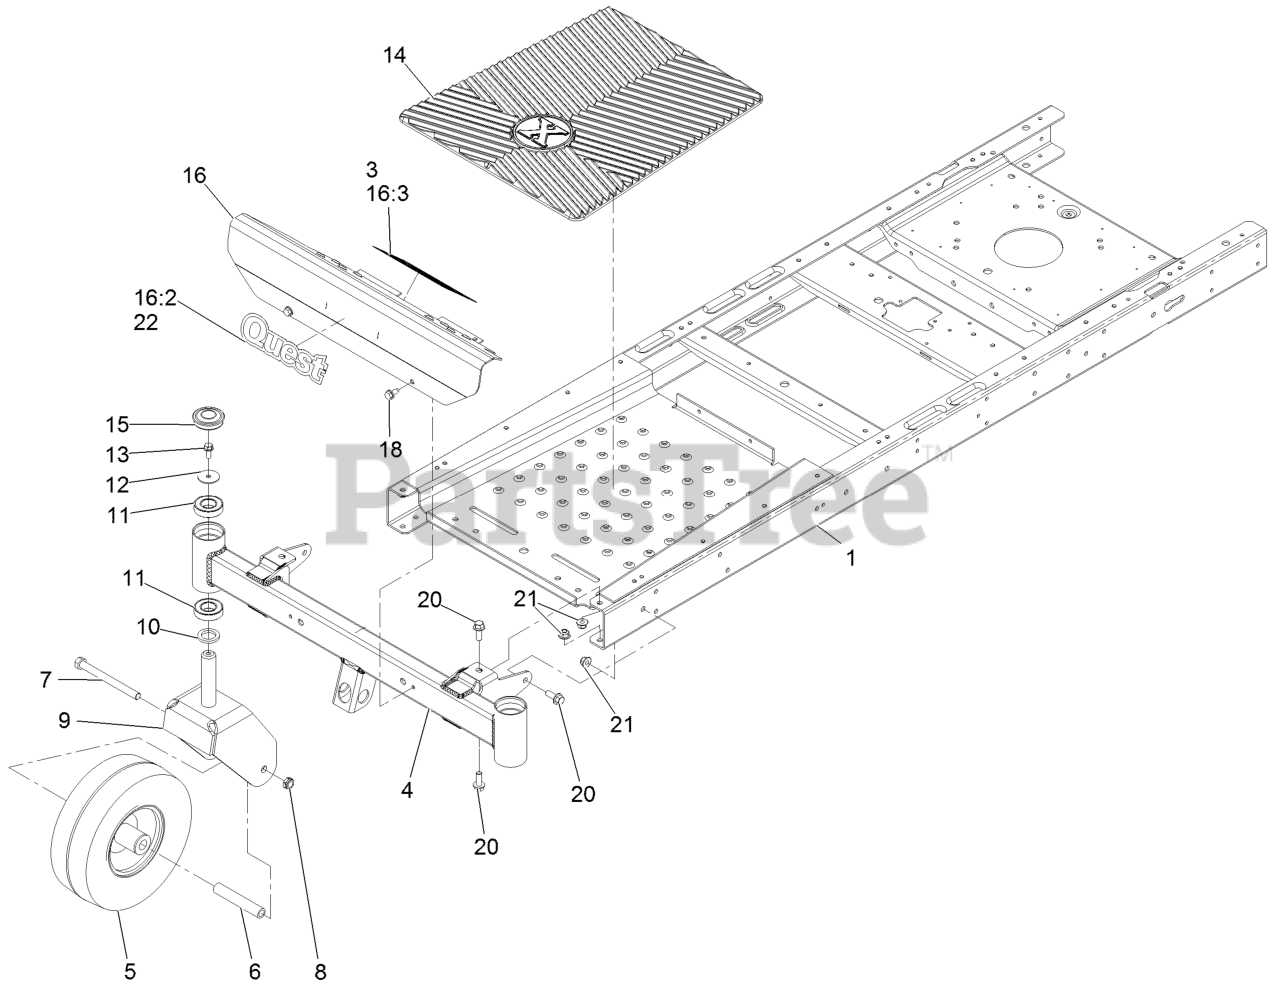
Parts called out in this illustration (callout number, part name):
1	FRAME ASM
3	DECAL-DANGER
4	AXLE-FRONT, NARROW
5	CASTER WHEEL ASM
6	BUSHING-SPANNER
7	SCREW-HH
8	NUT-HEX
9	FORK-CASTER
10	WASHER-THRUST
11	BEARING-BALL
12	WASHER-FLAT
13	SCREW-HHF
14	MAT-FLOOR
15	CAP-GREASE
16	FOOTREST ASM
16:3	DECAL-DANGER
18	Screw-HWH 5/16-18 X 3/4 Tf
20	SCREW-HHF 3/8-16 X 1
21	NUT-HF, NI
